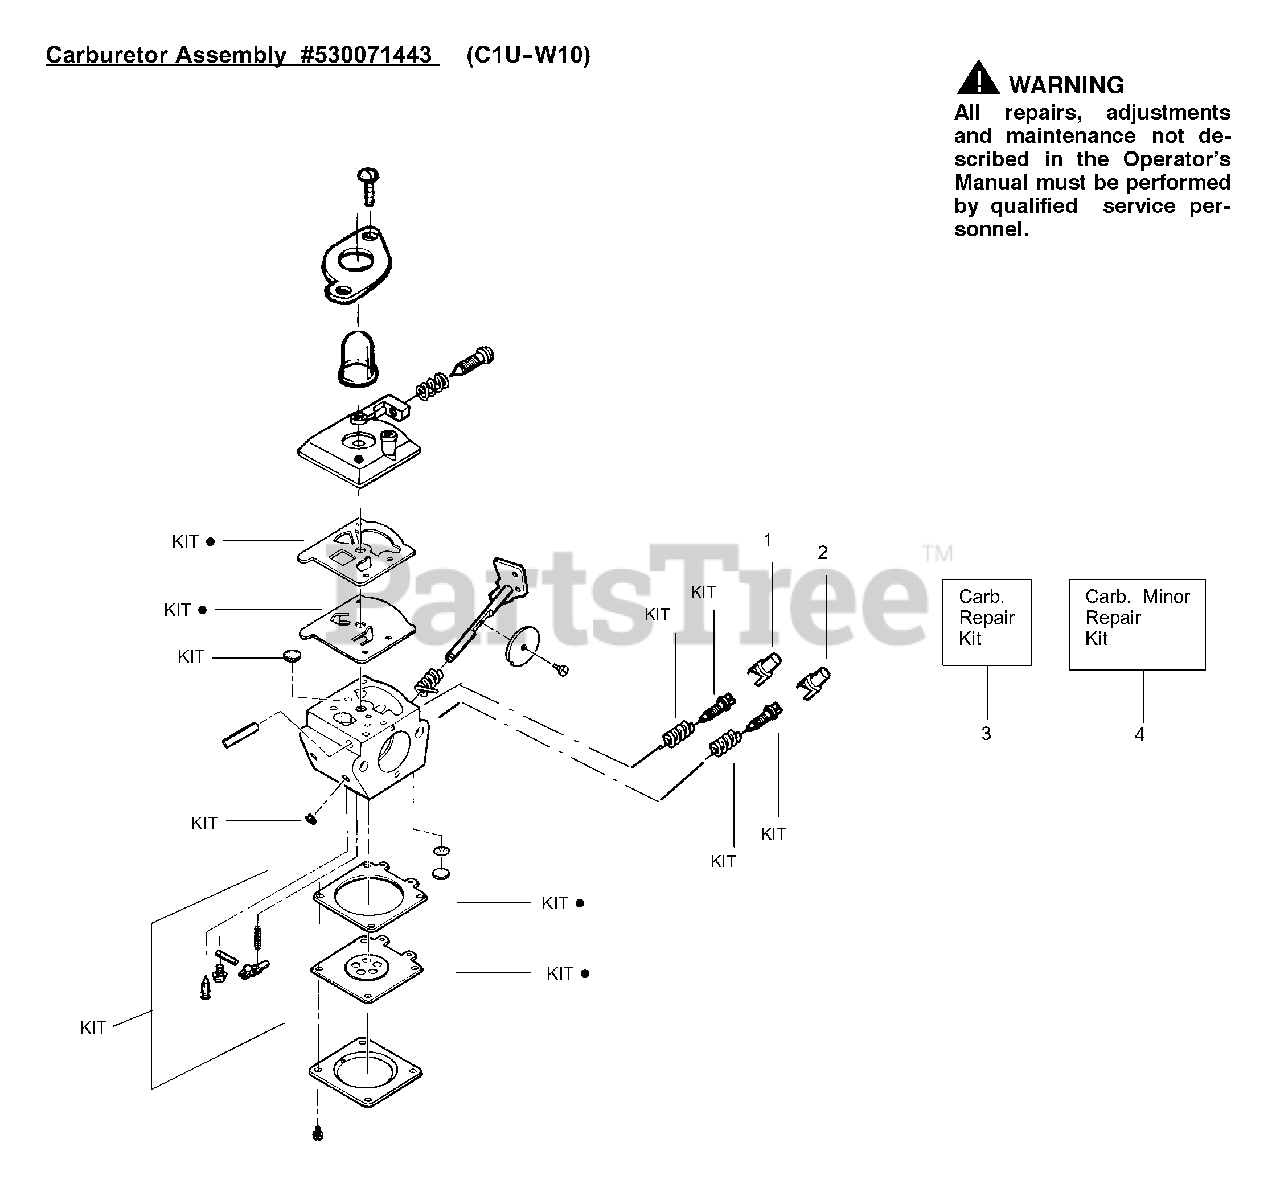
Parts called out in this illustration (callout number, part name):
1	Limiter Cap (low)
2	Limiter Cap (high)
3	Kit-Carburetor Repair
4	Kit-Carburetor Minor Repair
530071443	Carburetor Assembly - C1U-W10
